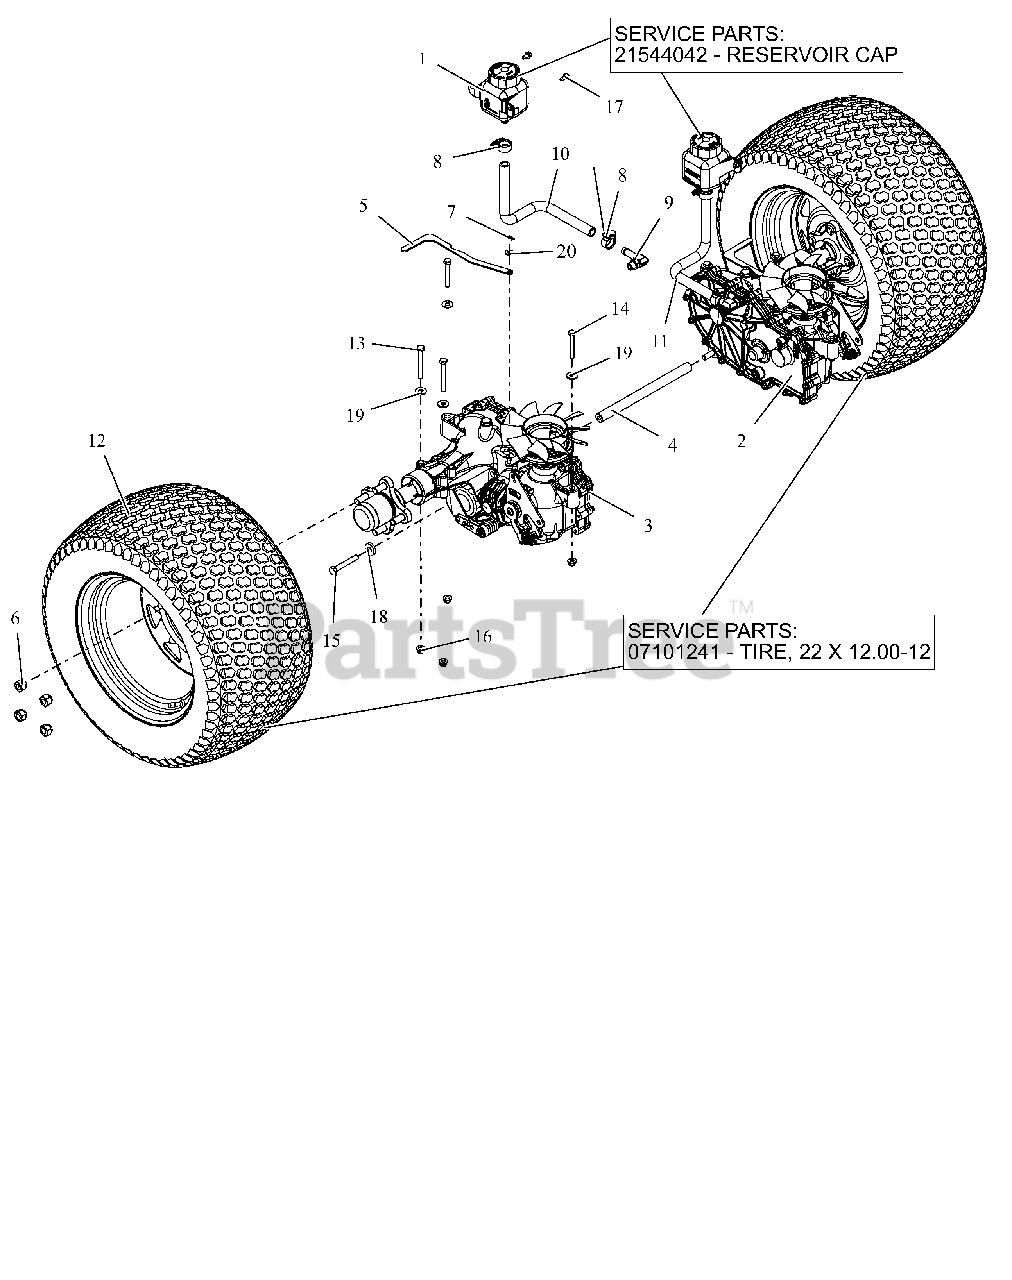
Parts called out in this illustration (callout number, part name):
1	TANK, EXPANSION
1	CAP, HYDRO RESERVOIR REPLAC.
2	TRANSAXLE, ZT3100 LH
3	TRANSAXLE, ZT3100 RH
4	SHAFT, TRANSAXLE SUPPORT
5	BRKT, VALVE DUM
6	NUT, WHEEL .50-20 ZCC
7	PIN, HAIR #225 .072X1.09
8	CLAMP,.88 DIA. HOSE
9	FITTING, HYD (90 DEG)
10	HOSE, FORMED EXPANSION -HD RH
11	HOSE, FORMED EXPANSION -HD LH
12	ASM, WHL/TIRE 22X12.00-12 K500
12	TIRE, 22X12.00-12
13	BLT, HEX .31-18X2.75 G5 ZCC
14	BLT, HEX .31-18X2.25 G5 ZCC
15	BLT, HEX .38-16X2.50 G5 ZCC
16	NUT,NYL-FLG .31-18 GF ZCC
17	SCR-TAP .25-20X.50 HWH ZCC
18	WSHR, FLT .406X1.00X.188 ZCC
19	WSHR,FLT .375X.875X.083 ZCC
20	WSHR,FLT .281X.625X.065 ZCC
